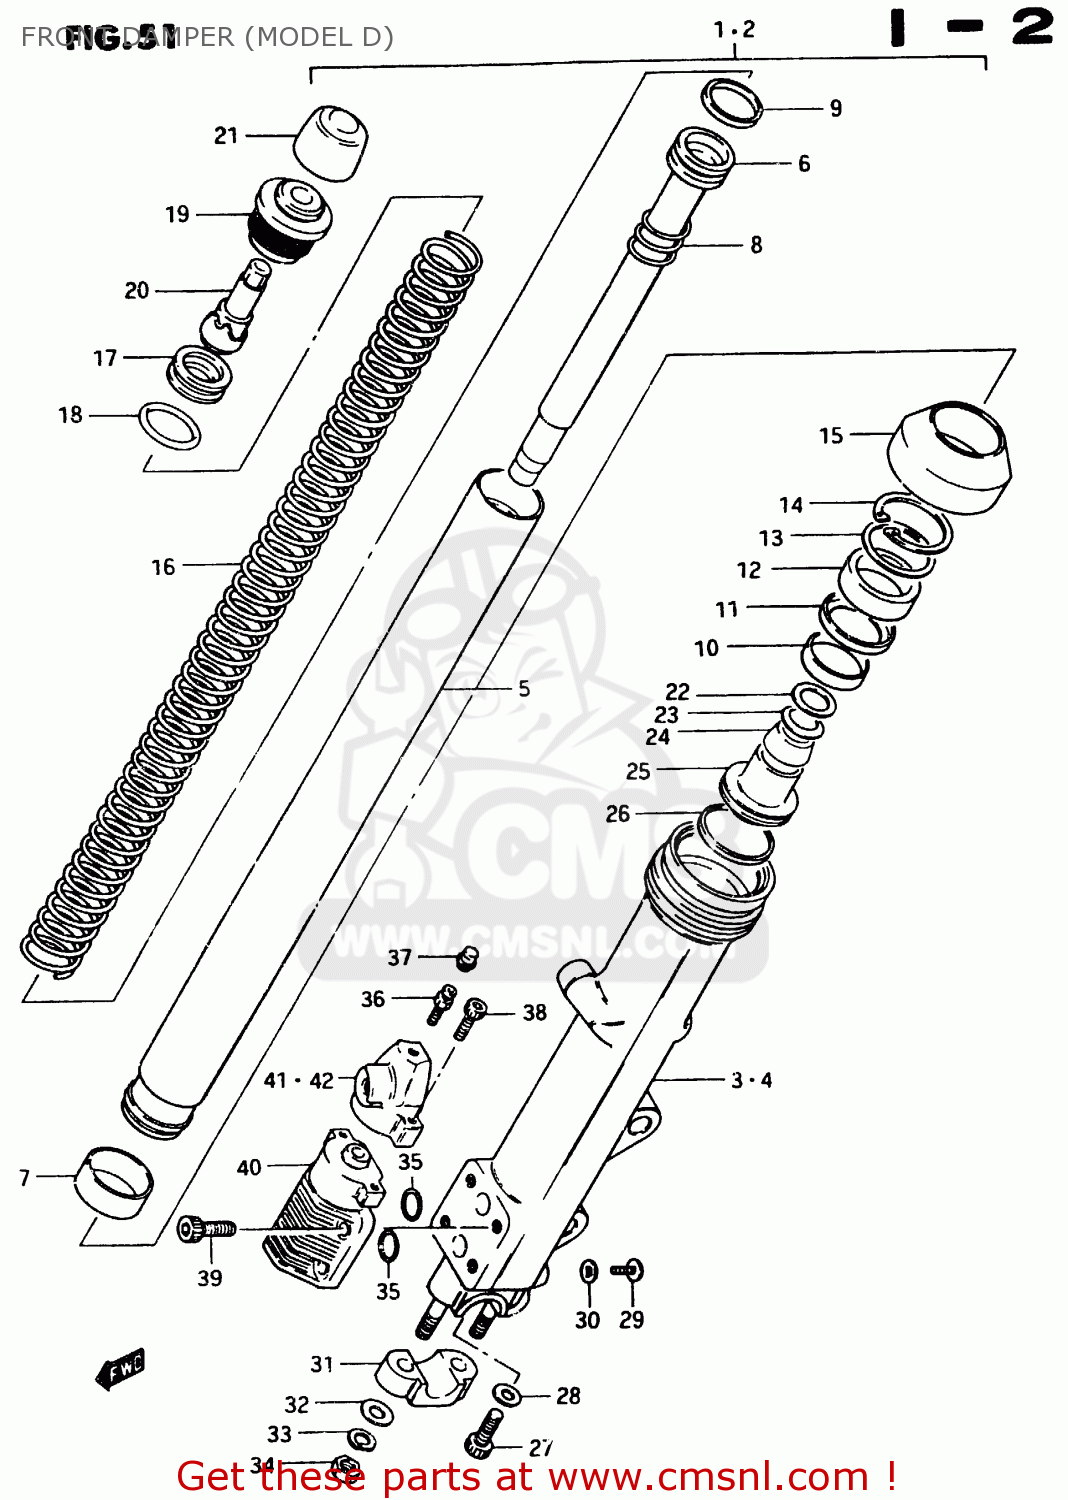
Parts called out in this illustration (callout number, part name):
1	DAMPER ASSY, RH
2	DAMPER ASSY, LH
3	TUBE,OUTER,RIGHT
4	TUBE,OUTER,LEFT
5	INNER TUBE
6	CYLINDER
7	PISTON
8	SPRING,FORK REBOUND
9	RING,PISTON
10	BUSHING,GUIDE
11	SPACER,SEAL
12	OIL SEAL,FRONT FORK
13	RING,BACKUP
14	CIRCLIP,INNTERNAL
15	BOOT
16	SPRING
17	SEAT,FRONT FORK SPRING
18	O RING
19	CAP,FORK INNER TUBE
20	ADJUSTER,SPRING
21	CAP
22	VALVE
23	SPRING,VALVE
24	VALVE,OIL LOCK PIEACE
25	PIECE,OIL LOCK
26	RING,PISTON
27	BOLT(8X27)
28	GASKET (NAS)
29	SCREW 4X6
30	GASKET (NAS)
31	HOLDER,AXLE
32	WASHER
33	WASHER,LOCK,8.
34	NUT
35	O RING,FR FORK
36	BREATHER
37	CAP
38	BOLT
39	BOLT
40	VALVE SET,MODULATOR
41	PLUNGER SET,MODULATOR,RIGHT
42	PLUNGER SET,MODULATOR,LEFT
